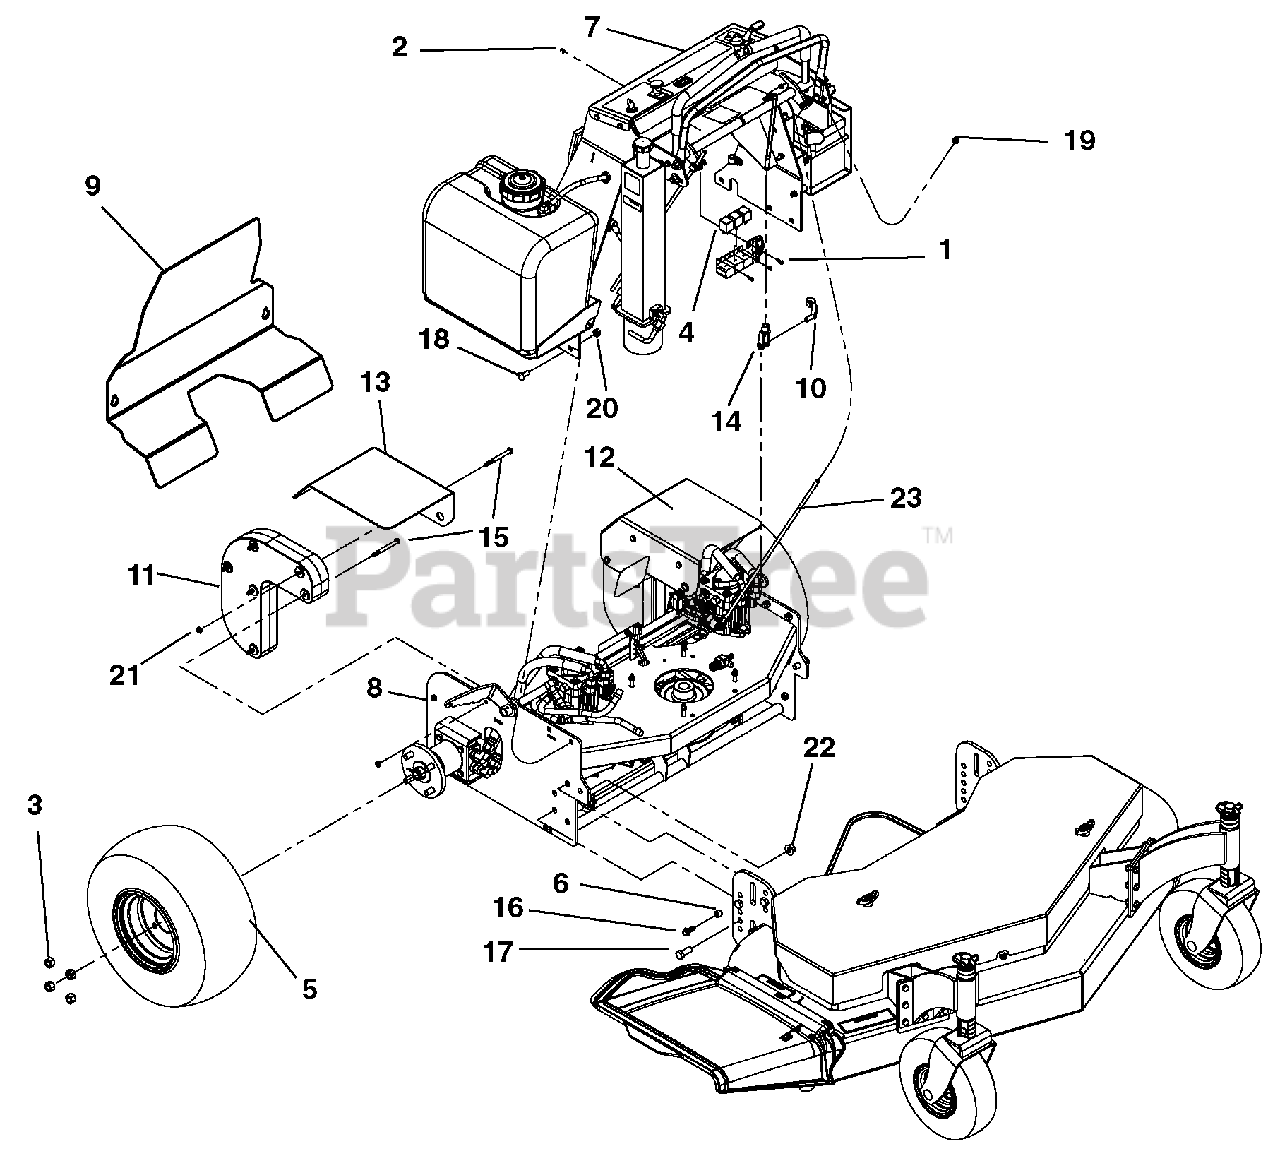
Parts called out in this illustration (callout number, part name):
1	Bolt, Hex 8-32 x .5
2	Nut, Locking, Nylon 8-32
3	Nut, Lug .5-20
4	Relay, ISO Mini Electric
5	Assembly, Tire/Wheel 18/8.5 x 8
6	Spacer, .625 x .120 x .400
7	Assembly, Console (See Console Components on page 23.)
8	Power Unit (See Engine, Hydraulic and Mainframe Assembly on page 10.)
9	Foot Guard w/Decals S/O
10	Pin, CVS SPG 3/8" Yoke
11	Weight, Cast Drilled
12	Fender, LH
13	Fender, RH
14	Yoke, 3/8-24 RH Adjustable
15	Bolt, .31-18 x 3.25 Grade 5
16	Bolt, .38-16 x 1.00 Grade 8
17	Bolt, .50-13 x 1.25 Grade 5
18	Bolt, Round Head Square Neck .38-16 x 1.00
19	Nut, Hex .312-24
20	Nut, Locking, .375-16
21	Nut, Locking, Nylon .312-18
22	Nut, Locking .50-13
23	Control Rod
